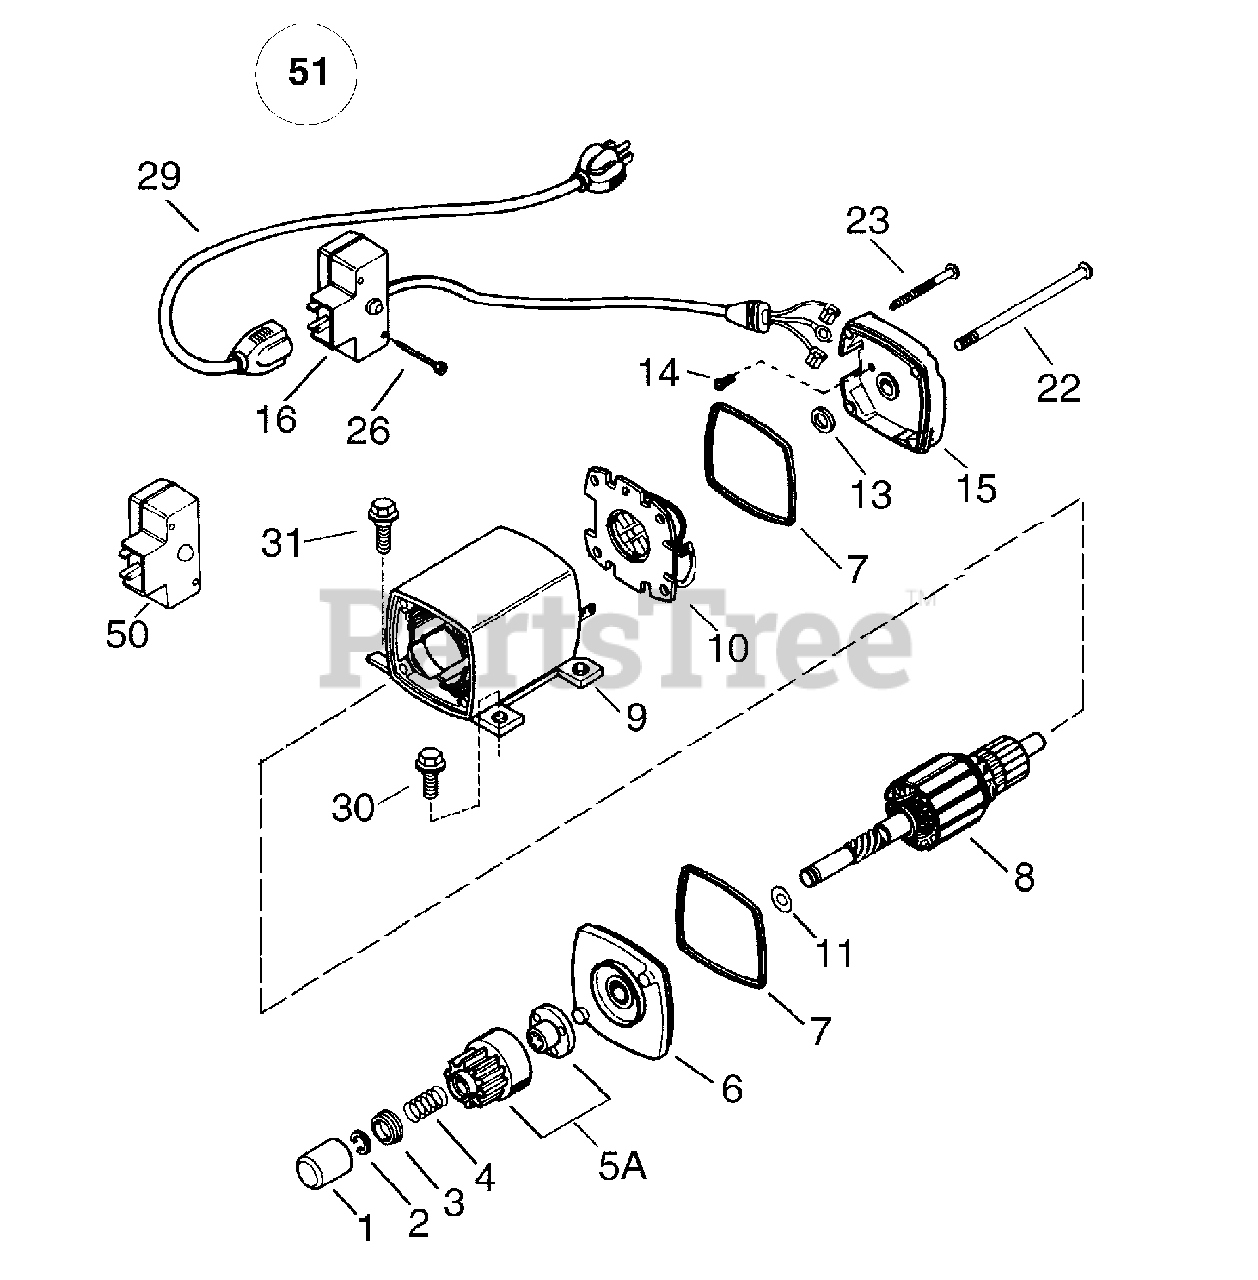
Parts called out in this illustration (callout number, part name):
1	Dust Cover
2	Retainer Ring
3	Spring Retainer
4	Anti-Drift Spring
5A	Nut & Gear
6	Drive End Cap Ass'y
9	Housing Ass'y
10	Brush Card Ass'y
11	Thrust Washer
13	Thrust Washer
14	Ground Screw
15	Commutator End Cap Ass'y
16	Switch Box Ass'y
22	Case Bolt
23	Grounding Screw
26	Screw, 6-32 x 2-1/2"
29	Extension Cord (10' 6")
30	Screw, Torx T-30, 1/4-20 x 1/2"
31	Screw, 1/4-20 x 1/2"
50	Switch Repair Kit
51	Electric Starter (110 Volt)
